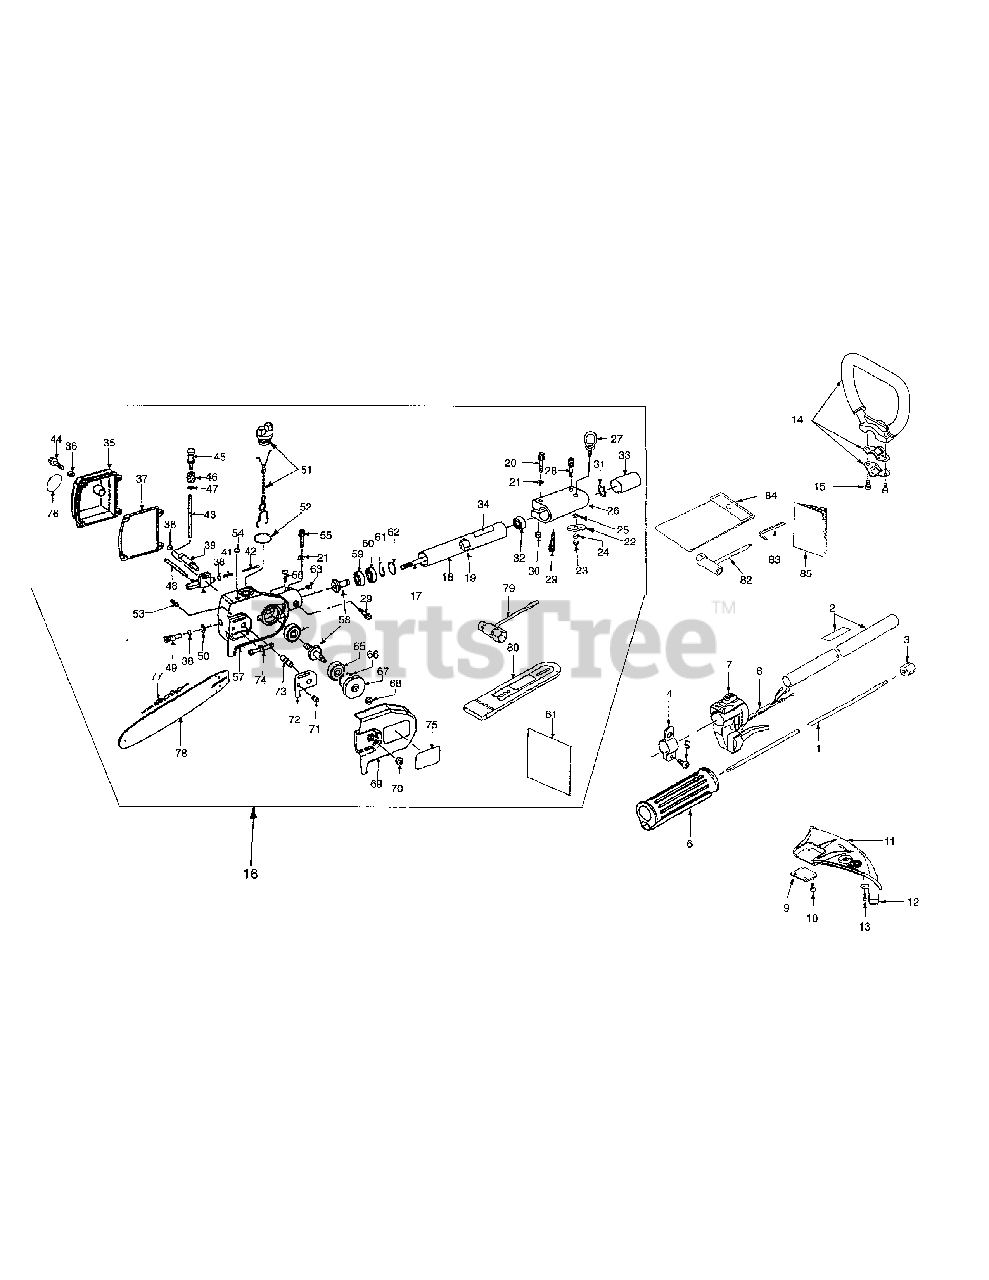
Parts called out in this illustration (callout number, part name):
1	Shaft, Drive
2	Pipe, Complete
5	Bolt, 1M6x14
7	Lever Assembly, Throttle
8	Wire Complete, Throttle
11	Deflector Assembly, Plastic
14	Handle, Loop
16	Pole Saw Assy
17	Shaft, Drive
21	Spring Washer
22	Nut, Knob
23	Cap Nut
25	Washer
32	Ball Bearing
34	Caution Plate
35	Cover, Oil Tank
40	Pump, Lubricating Oil
42	Piston, Oil Pump
45	Filter Ass'y Oil
46	Filter, Oil
47	Washer
49	Adjuster, Oil Pump
51	Cap, Oil Filler
59	Ball Bearing
60	Ball Bearing
64	Ball Bearing
65	Ball Bearing
72	Plate, Guide
76	Caution Plate
77	Chain; 9,52mm (3/8 inch)
78	Bar, Chain; 250mm (10 inch 3/8)
79	Box, Spanner
80	Cover, Chain
81	Manual Operator's
82	Wrench, Spanner Box 19
83	Wrench, Key, 4mm
